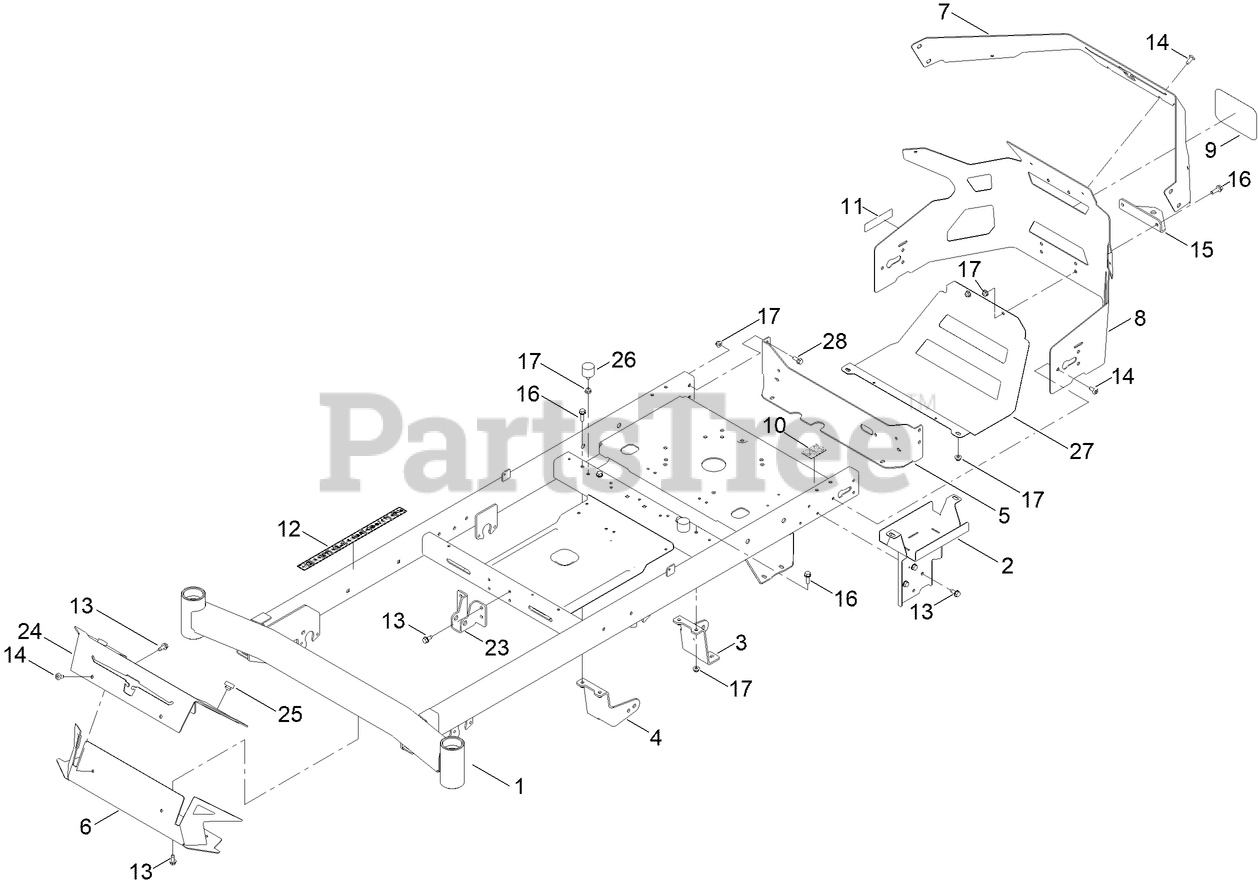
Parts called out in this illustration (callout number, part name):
1	SERVICE ASM-FRAME, TC
2	WA-BATTERY MOUNT
3	MOUNT-DRIVE, LH
4	MOUNT-DRIVE, RH
5	PLATE-MOUNT
6	FOOTREST-TOP
7	PLATE-REAR CLADDING TC
8	GUARD-ENGINE TC
9	DECAL
10	DECAL-BYPASS
11	DECAL-SPARK ARRESTER
12	DECAL-WARNING
13	SCREW-HWHTF
15	BRACKET-HITCH
16	SCREW-HHF
17	NUT-HF
23	BRACKET-MOUNT DAMPER, LOWER
24	PLATE-KICK, MR
25	BUMPER-RUBBER
26	BUMPER-RUBBER
27	GUARD-MUFFLER [BLACK]
28	SCREW-HHF
